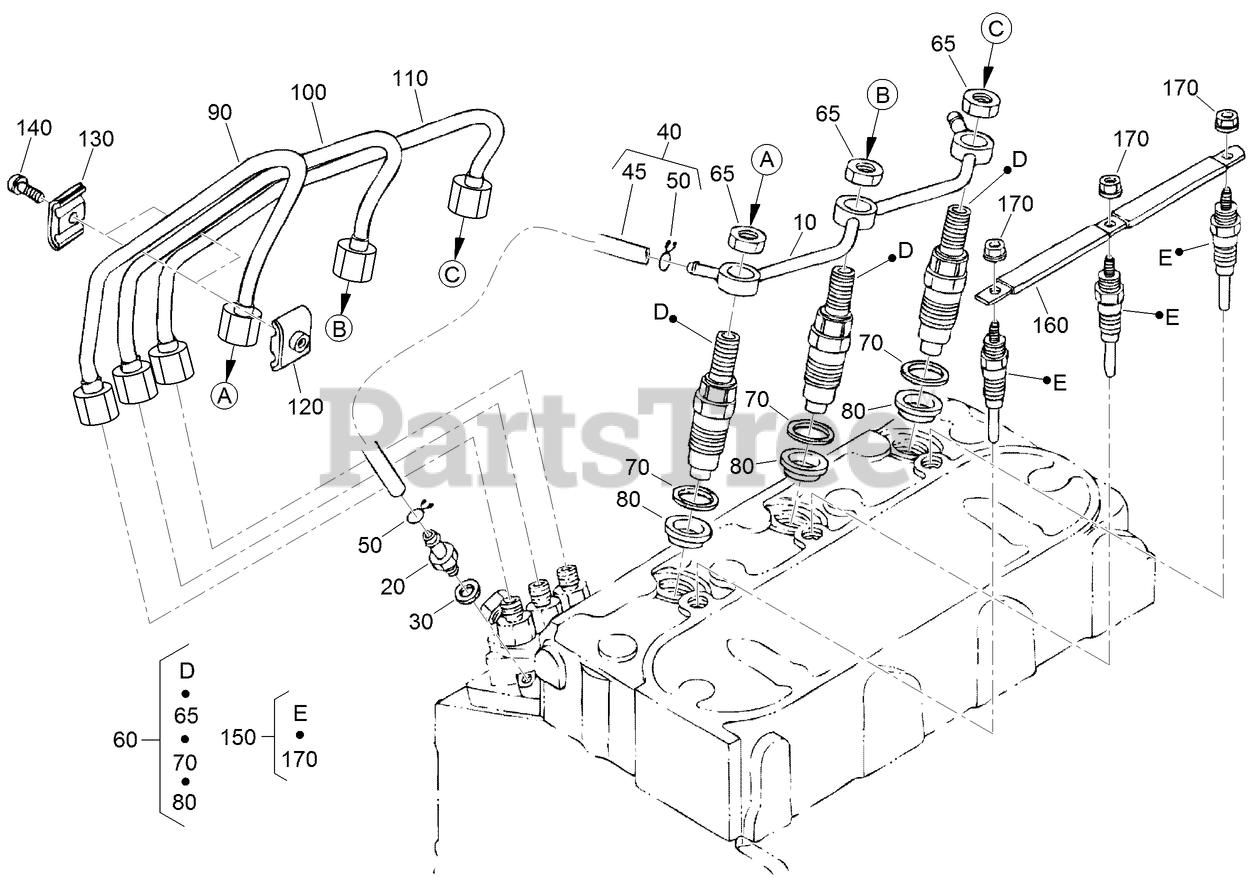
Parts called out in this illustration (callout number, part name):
10	OVERFLOW PIPE ASM
20	SCREW-BLEEDER, AIR
30	GASKET
40	OVERFLOW PIPE ASM
45	PIPE-OVERFLOW
50	CLIP-PIPE
60	NOZZLE HOLDER KIT
70	GASKET
80	SEAL-HEAT
90	PIPE INJECTION
100	PIPE INJECTION
110	PIPE INJECTION
120	CLAMP-PIPE
130	CLAMP-PIPE
140	SCREW (W/WASHER)
150	PLUG-GLOW
160	CORD-PLUG, GLOW
170	NUT-FLANGE
